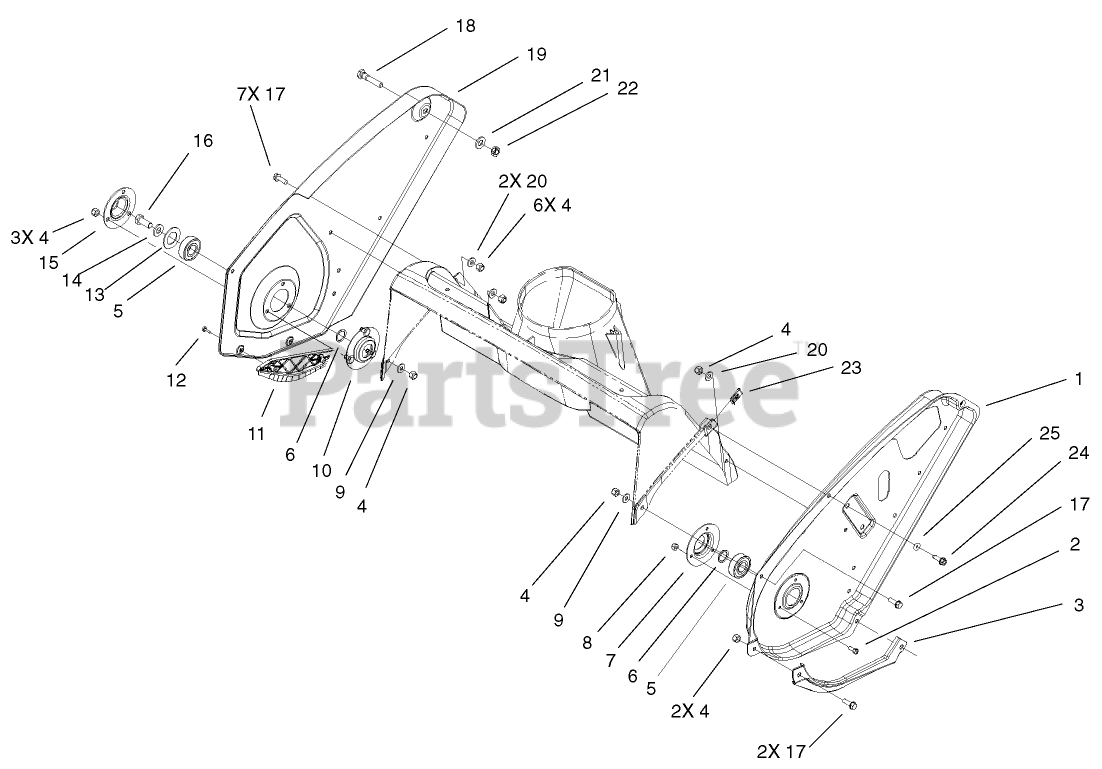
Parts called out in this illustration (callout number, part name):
1	SIDEPLATE-LH
2	SCREW-SHH
3	GUARD-ROTOR, LH
4	NUT-LOCK, NI
6	WASHER-THRUST
7	FLANGE-BEARING
8	NUT-LOCK, NI
9	WASHER-FLAT
10	FLANGE-BEARING
11	GUARD-ROTOR, RH
12	SCREW-PPH
13	WASHER-RUBBER
14	WASHER-FLAT
15	RETAINER-BEARING
16	SCREW-HHF
17	SCREW-HWH
18	PIN-TANK
19	SIDEPLATE-RH
20	WASHER-FLAT
21	WASHER-FLAT
22	NUT-LOCK, CONE
23	NUT-SPEED
24	SCREW-HWHTF
25	O-RING
